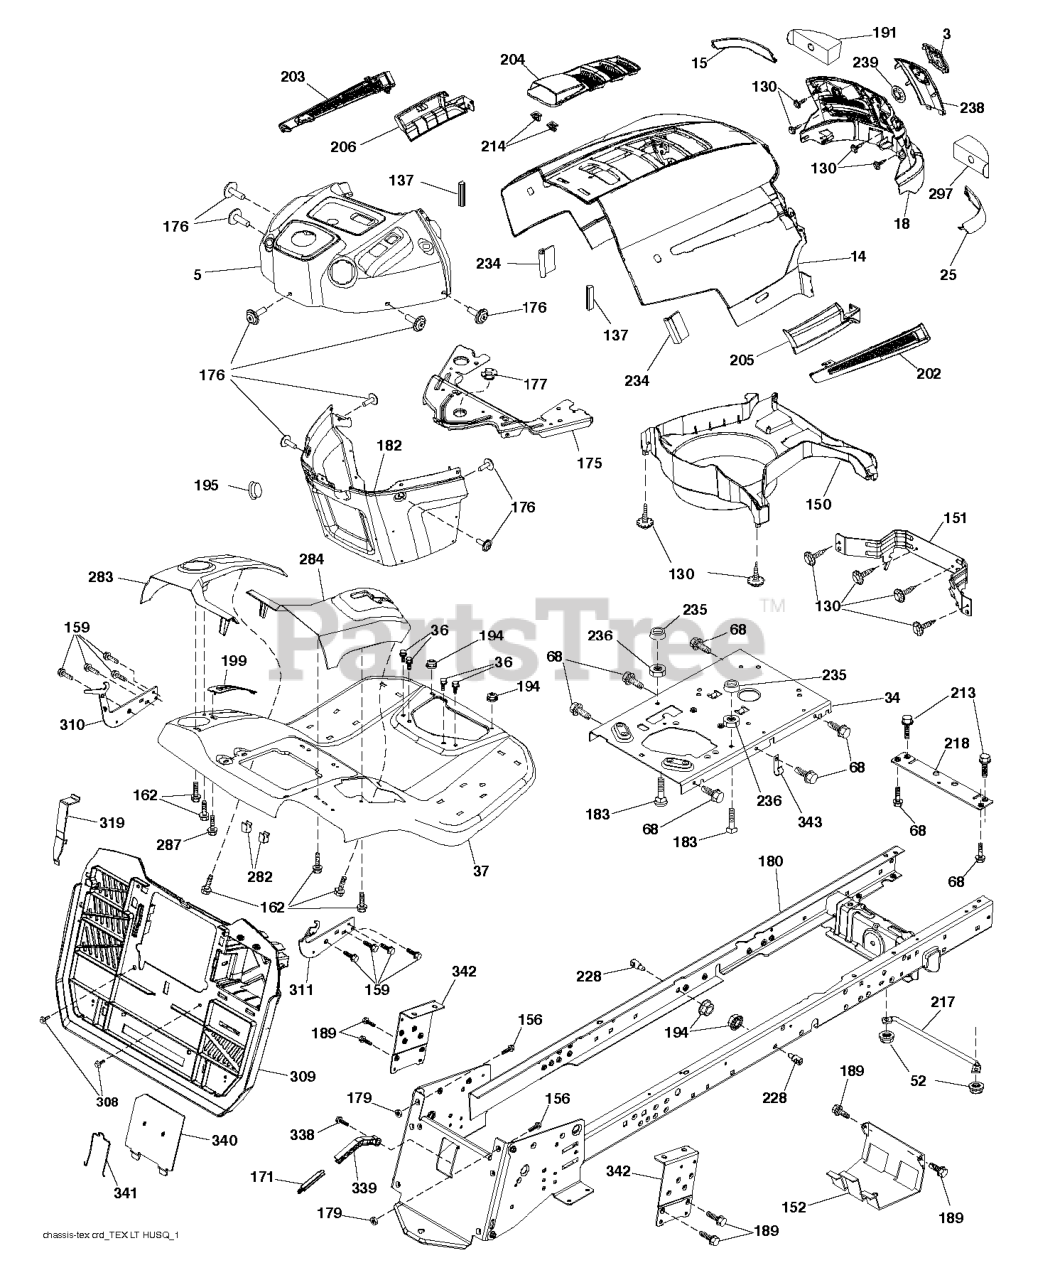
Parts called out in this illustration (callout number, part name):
3	RP LOGO
5	DASH
14	HOOD.HUSQVARNA.LT.MS422
15	LENS.HUSQVARNA LT.LH
18	GRILLE.SVC.HUSQVARNA.LT.GREY
25	LENS.HUSQVARNA LT.RH
34	PLATE.ENGINE.WELDED.CHASSIS
36	SCREW 5/16"
37	FENDER.TEX.SRD.CRD.BASE
52	LOCKNUT
68	Screw 5/16-18 x 1/2 Hex, Self Tapping 5/16-18 x 1/2
130	SCREW.#10 X 0.750.BOS
137	BUMPER DASH
151	BRACKET PIVOT
152	SHIELD.BROWNING.W/TEX
159	SCREW, 3/8-16X3/4
162	SCREW.HI-LO.CONSOLE
171	EXTENSION.BAGGER.FULL.
175	CROSSMEMBER
176	SCREW.#10-24X5/8.RN.QU
177	BUSHING STEERING
182	DASH.LOWER.PREDATOR LT
183	BOLT.5/16-18X1-1/4 FULL THD
189	SCREW
191	INSERT.REFLECTIVE.RH.
194	NUT LOCK HEX FLANGE 5/16-18
195	PLUG DASH
199	PLATE DECK LIFT
202	VENT SIDE HOOD LH
203	VENT SIDE HOOD RH
204	VENT TOP HOOD
205	SKIRT SIDE RH
206	SKIRT SIDE LH
213	BOLT
214	CLIP.RETAINER.TINNER.
217	ROD.PIVOT.HOOD
218	X-PIECE.HOOD.STOP.NON/
228	STUD.FASTNER.W/ANTI-ROTATE
234	BUMPER.HOOD.TEX.HUSQVARNA
235	SPACER FENDER
236	NUT.CENTERLOCK.5/16-
238	TRIM
282	CLIP.RETAINER.CONSOLE.LT.HUSQ
283	CONSL.DECKLIFT.LH.SRD.TEX.CRD
284	CONSL.SHIFT.GEAR.RH.SRD.GREY
287	SCREW 1/4X20
297	INSERT REFLECTIVE
308	BOLT.5/16-18UNCX3/4 W/SEMS.BLK
310	LH.ADJUST.HANGER.BRACKET.ASM
311	RH.ADJUST.HANGER.BRACKET.ASM
319	BRACKET.ACTUATOR.BAGGER.SRD
338	BOLT BOLT SHOULDER
339	LEVER.BAGGER.FULL.TEX.
340	DOOR.PNT.BATTERY.TRY.TEX.CRD.
341	LATCH
342	BELT GUIDE
343	CLIP CLIP
